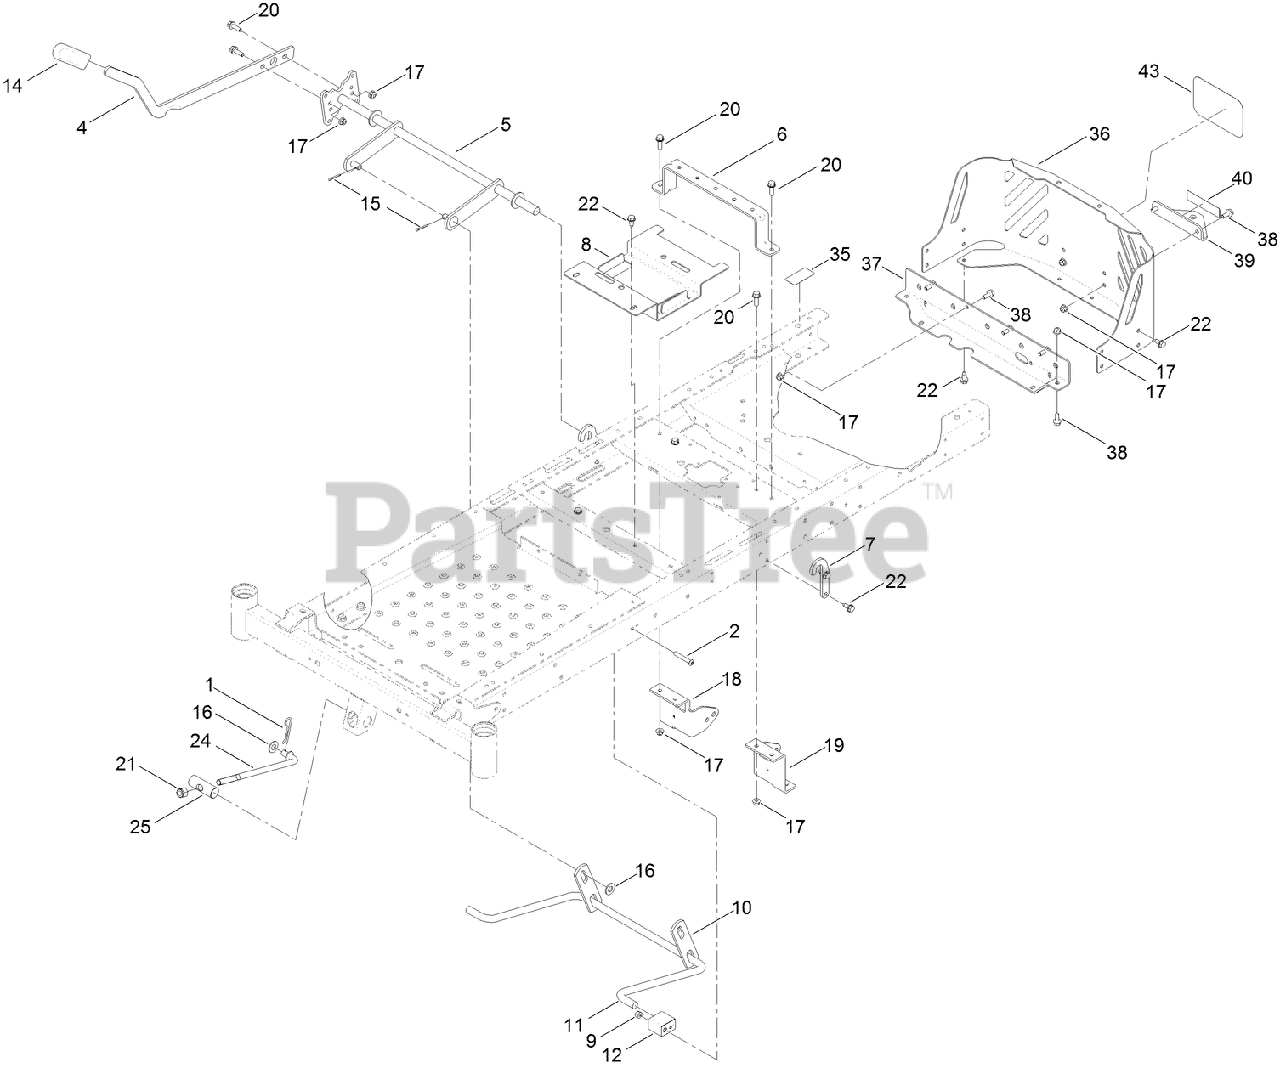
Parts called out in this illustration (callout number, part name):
1	PIN-COTTER
2	SCREW-HSBH
4	LEVER-LIFT
5	LIFT-DECK, NARROW
6	BRACE-SEAT, REAR (NARROW)
7	BRACKET-LIFT
8	BRACKET-BATTERY
9	NUT-LOCK, NI
10	LINK-LIFT
11	ARM-LIFT, REAR
12	BLOCK-PIVOT
14	GRIP-LEVER
15	PIN-COTTER
16	WASHER-FLAT
17	NUT-HF, NI
18	MOUNT-HYDRO, FRONT (RH)
19	MOUNT-HYDRO, FRONT (LH)
20	SCREW-HHF
21	NUT-HEX
22	SCREW-HWHTF
24	ROD-MOUNT, DECK
25	PIN-PIVOT
35	DECAL-BYPASS
36	GUARD-ENGINE, NARROW
37	CROSSMEMBER-REAR, NARROW
38	SCREW-HHF
39	BRACKET-HITCH
43	DECAL
